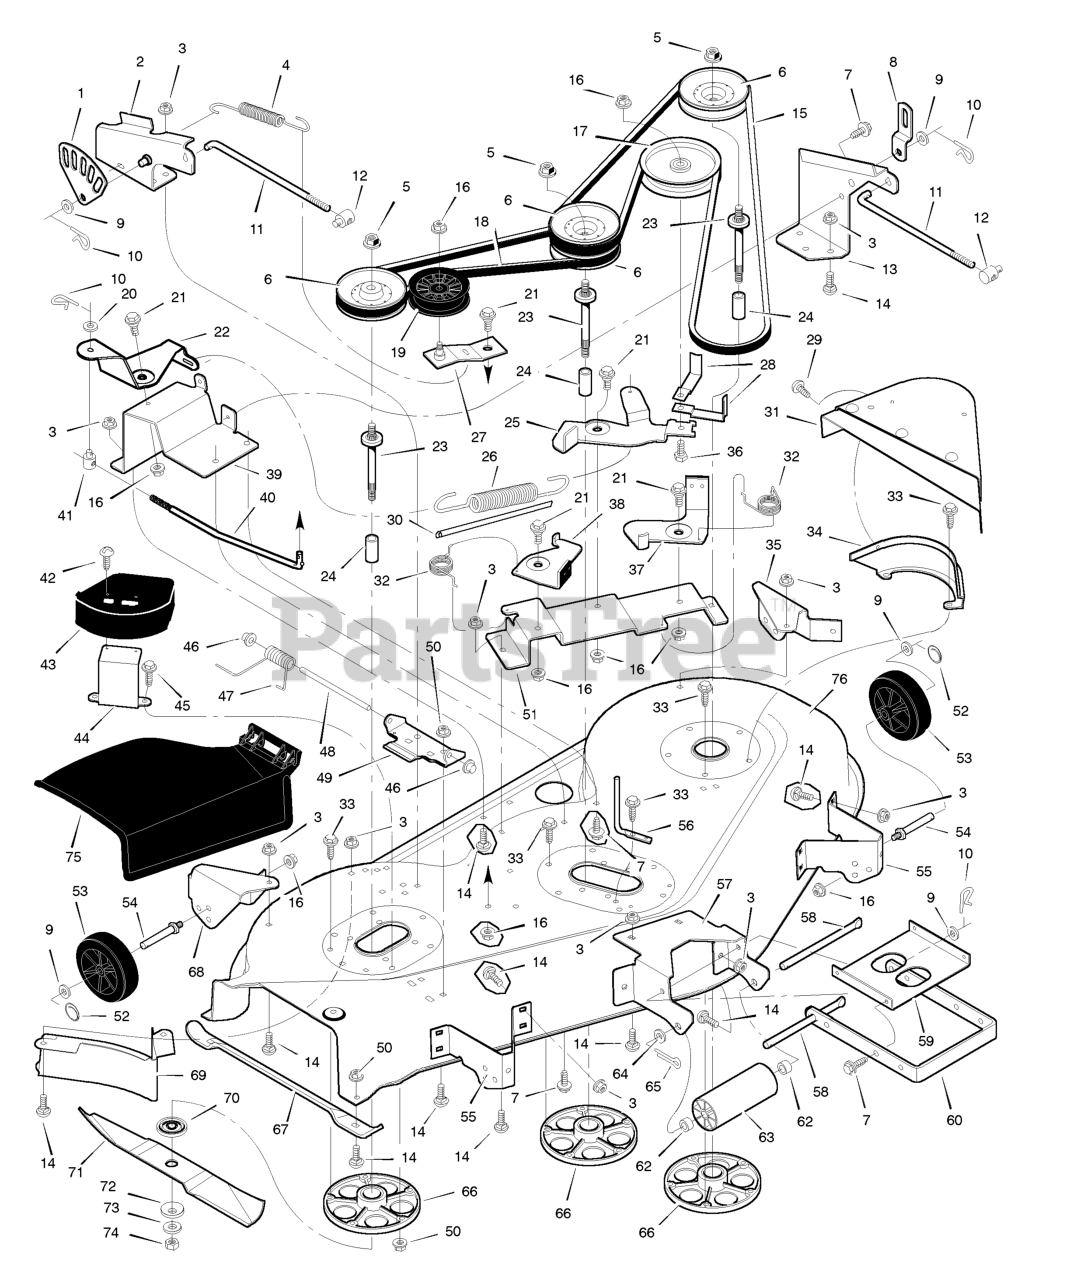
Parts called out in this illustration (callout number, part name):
1	Plate, Adjuster
2	Bracket Assembly, RH Lifter
3	Nut, Flange
4	Spring, Extension
5	Nut, Flange
6	Pulley
8	Link, Suspension
10	Hair Pin
11	Rod, Adjusting
12	NUT, Adjusting, 1/2-13
13	Bracket Assembly, LH Lifter
14	Bolt, Carriage
15	Belt, Primary Blade Drive
16	Nut, Flange
17	Pulley, Idler
18	Belt, Secondary Blade Drive
19	Pulley, Backside Idler
21	Bolt, Shoulder
22	Bellcrank, PTO
23	Shaft, Splined
25	Arm-Idler, Clutching
26	Spring, Extension
27	Arm Assembly, RH Idler
28	Guide, Belt
30	Strip, Indicator
31	Cover, LH Pulley and Extension
32	Spring, Torsion
33	Screw
34	Bracket, Pulley Cover
35	Bracket, Left Rear Gauge Wheel
36	Bolt, Idler Pulley
37	Brake Assembly, Left
38	Brake Assembly, Right
39	Bracket, Bellcrank
40	Link, PTO
41	Nut, Adjusting
42	Screw
43	Cover, Right Pulley
44	Bracket, Right Pulley Cover
45	CAPSCREW, Hex Head, 5/16-18 x 1
46	Push On Cap
47	Spring, Torsion
48	Rod, Deflector
49	Bracket, Hinge
50	Nut, Flange
51	Plate, Brake Arm
52	Ring, Locking
53	Wheel, Gauge
54	BOLT, Gauge Wheel
55	Bracket, Front Gauge Wheel
56	Guide, Belt
57	Bracket, Front Deck
58	Rod, Roller
59	Stiffener
60	Bracket, Front Suspension
65	Pin, Cotter
66	Housing, Jackshaft
67	Guard, Horn
68	Bracket, Right Rear Gauge Wheel
69	Baffle, Housing
70	Adapter, Blade
71	Blade
72	Washer, Belleville
74	Nut, Hex
75	Deflector, Chute
76	Housing, Blade
